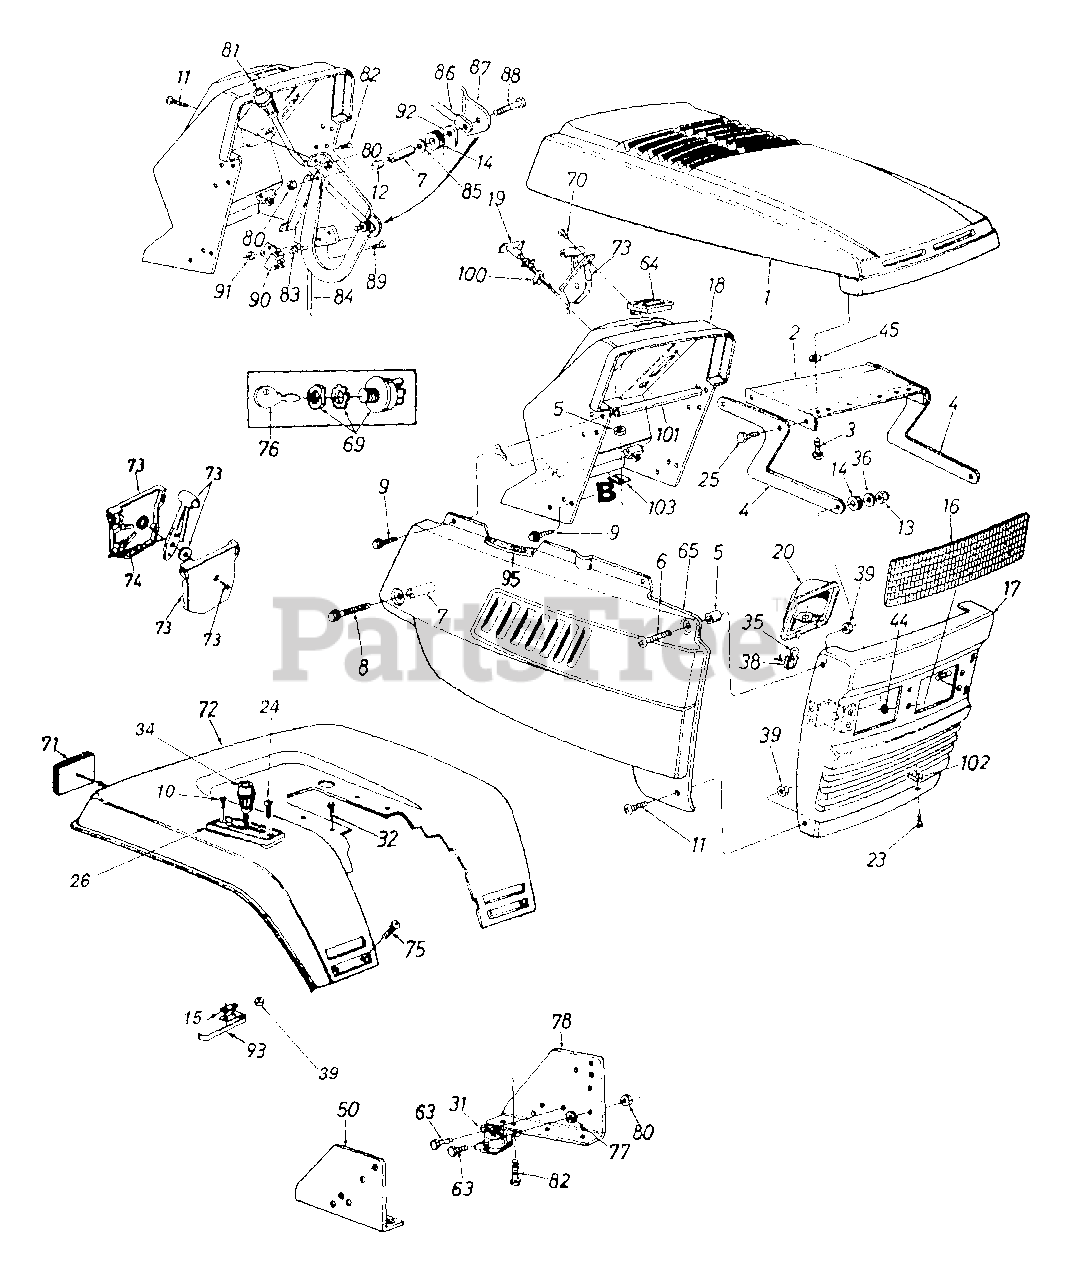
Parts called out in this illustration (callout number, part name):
1	Hood (Red)
6	Truss Hd. Mach. Scr. 1/4-20 Thd.
7	Spacer .26" I.D. x .375"
8	Hex Wash. TT-Tap Scr. 1/4-20 x 1.75" Lg
9	Hex T-Tap Scr. 1/4-20 x .75" Lg.
10	Hex Wash. Hd. AB-Tap Scr.
11	Truss Mach. Scr. 1/4-20 x .5" Lg.
12	Hex Ins. L-Nut 1/4-20 Thd.
13	Hex L-Nut 5/16-18 Thd.
14	Rubber Washer
15	Insulator Nut Plate
16	Headlight Lens
19	Choke Control
20	Headlight Housing
23	Hex Bolt 5/16-18 x .75" Lg.
24	Truss Mach. Scr. 1/4-20 x .75" Lg
25	Hex Wash. Hd. Scr. 1/4" x .5" Lg.
26	Selector Plate
31	Solenoid
32	Hex Hd. Rolling Scr. 5/16-24 x .75"
34	Shift Knob
35	Lamp
36	Bell-Wash. .34" I.D. x .87"
38	Socket
39	Hex Sems Nut 1/4-20 Thd.
44	Speed Nut 5/16" I.D.
45	Fl-Wash. .406" I.D.
64	Ammeter
70	Truss Mach. AB-Tap Scr. #10 x .5" Lg.
71	Reflector
74	Throttle Control Wire 35" Lg.
75	Carriage Bolt 1/4-20 x .5" Lg.
76	Key
77	Ext. L-Wash. 1/4" I.D.
82	Hex Bolt 1/4-20 x .62" Lg.
83	Push Nut
84	PTO Rod
85	Fl-Wash. .281" I.D. x .73"
86	PTO Lever
89	Truss Mach. Scr. #10-24 x .5" Lg.
90	Safety Switch
91	Hex Nut #10-24 Thd.
92	PTO Bracket
93	Reverse Safety Switch
95	Trim Strip 12" Lg.
100	Retainer Clip
101	Dash Support Tube
102	U-Nut 5/16-18 Thd.
103	Dash Panel Fastening Tab
16725-0640	PANEL-SIDE RH - CO-OP GREEN (0640)
16725-0665	PANEL-SIDE RH - YARDMAN GREEN (0665)
16725-0691	PANEL-SIDE RH - BLACK JACK (0691)
17309B-0483	PANEL-SIDE-LH - CHARCOAL GRAY (0483)
17309B-0638	PANEL-SIDE-LH - MTD/TROY-BILT RED (0638)
